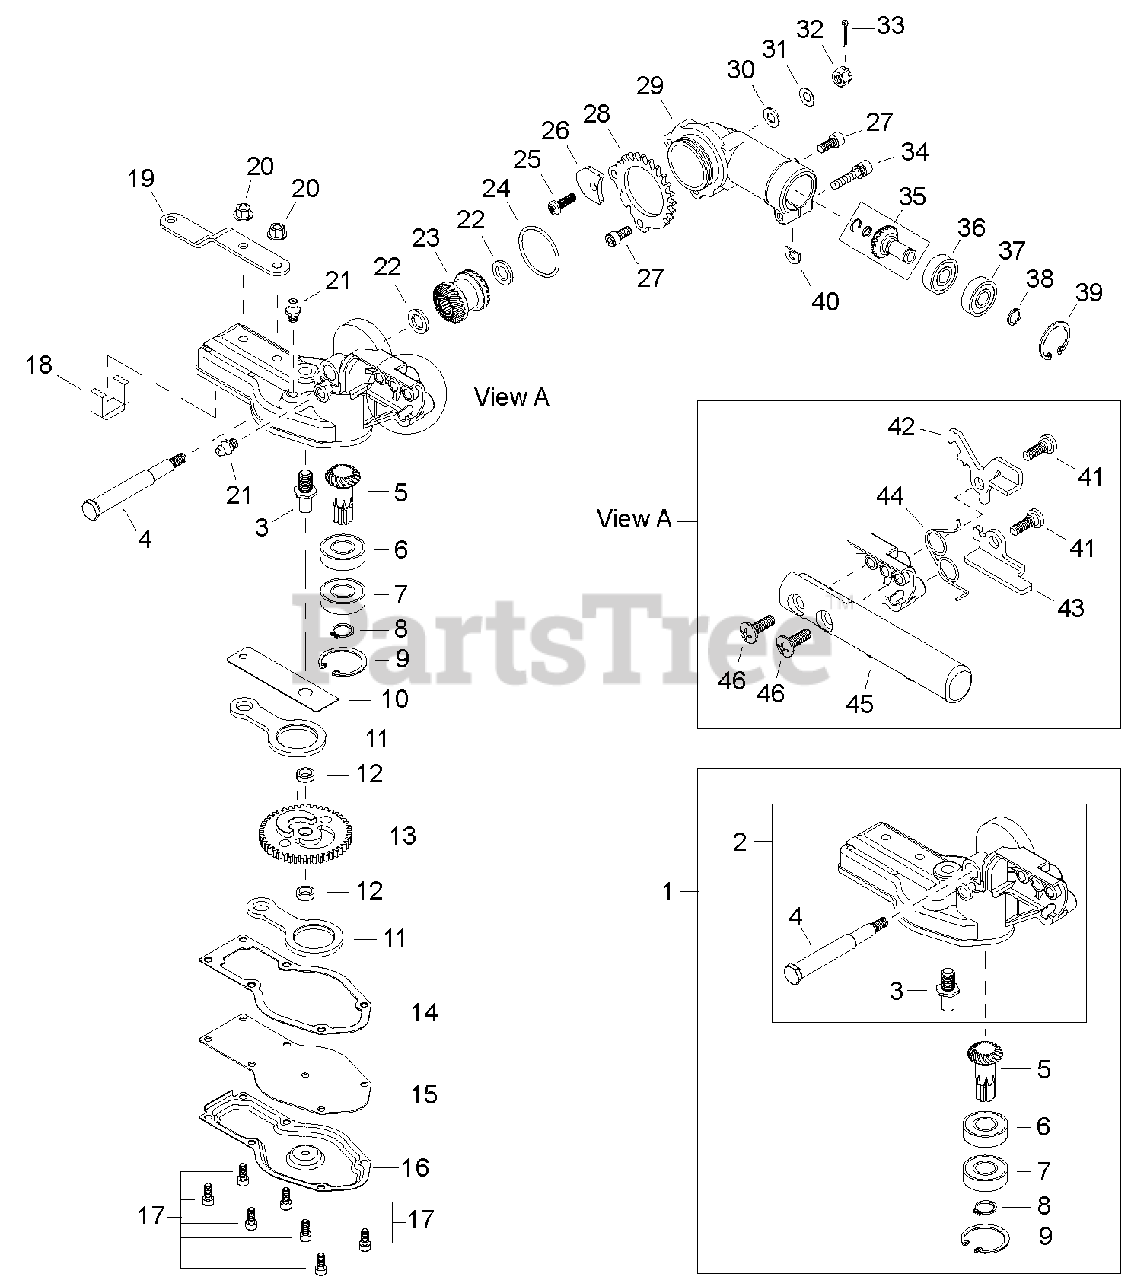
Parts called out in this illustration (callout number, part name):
2	GEAR CASE HOUSING ASSY
3	MAINSHAFT
5	SHAFT, PINION
6	BEARING, BALL 6001
7	BEARING, BALL 6001ZZ
8	RING, SNAP Ø12
9	RING, SNAP Ø28
10	PLATE, GUIDE
11	CONROD
11-1	GEAR CASE HOUSING KIT
11-4	SHAFT
12	SPACER Ø11ר8×3.4
13	GEAR, CAM
14	GASKET, GEAR CASE
15	SPACER
16	COVER, GEAR CASE
17	BOLT 4×10
18	PACKING, FELT
19	BRACKET, CUTTER
20	NUT, FLANGE M5
21	FITTING, GREASE
22	COLLAR Ø16ר10×L= 2
23	GEAR, BEVEL
24	O-RING
25	SCREW M5×16
26	PLATE, STOPPER
27	BOLT 5×12
28	RING, LOCKING
29	HOUSING, UPPER GEAR CASE
30	WASHER 6.5×13×1
31	WASHER, CONE M6
32	NUT M6
33	PIN, COTTER Ø1.6×15
34	BOLT M5×25
35	PINION SET, BEVEL
36	BEARING, BALL 609
37	BEARING, BALL 609ZZ
38	RING, SNAP
39	RING, SNAP Ø24
40	D-WASHER
41	BOLT M6
42	LEVER, LOCK
43	RELEASE, LOCK
44	SPRING, TORSION
45	LEVER, ADJUSTMENT
46	SCREW, TRUSS M6×20
